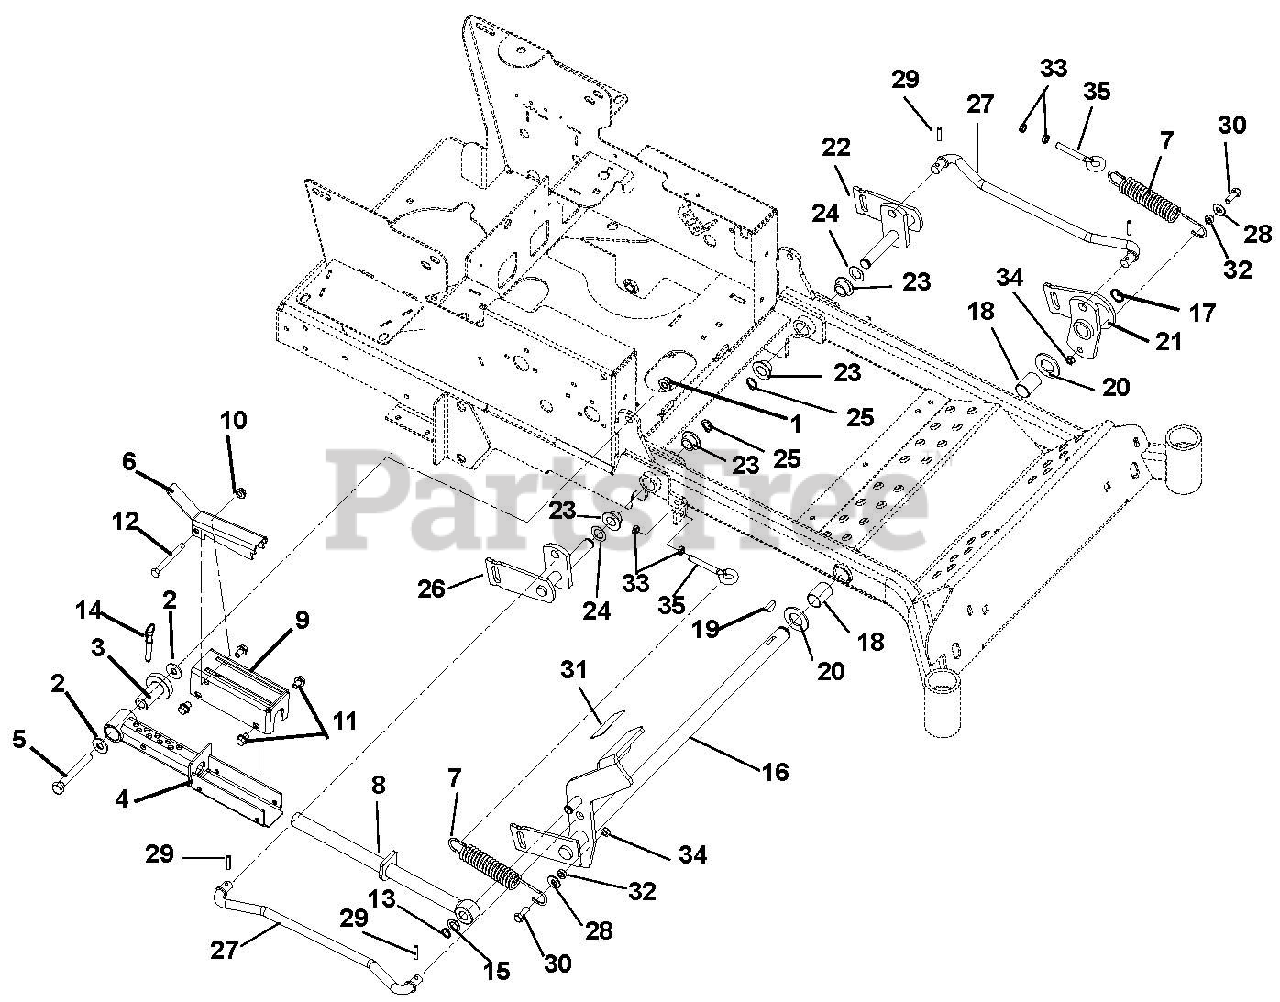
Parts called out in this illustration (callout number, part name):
1	Nut, Locking Top Flange .50-13
2	Washer, Flat Steel .531 x 1.25 x .10
3	Bearing, Pedestal
4	Weldment, Mechanical Lift
5	Bolt, Hex .50-13 x 3.75 Grade 5
6	Lock-Up, Mechanical Lift
7	Spring, Tension .162 x 1.25 x 8.25 Weldment 25
8	Weldment, Mechanical Lift Shaft
9	Weldment, Mechanical Lift Cover
10	Nut, Nyloc Flange 3/8-16
11	Screw, Tapping .38-16 x .50 Hex Washer Head
12	Bolt, Hex .38-16 x 3.25 Grade 5
13	Ring, Retaining External .625 x .050
14	Pin, Spring Ball .375 O.D. x 1.50
15	Washer, Flat Steel .630 x .005 x .062
16	Weldment, Foot Operated Deck Lift
17	Ring, Retaining External 1.00 x .078
18	Bushing 1.00 ID x 1.125 OD x 1.50
19	Key, Woodruff .25 x 1.00
20	Washer, Flat Steel 1.062 x 2.0 x .134
21	Weldment, Left Hand Mower Lift Arm
22	Weldment, Left Hand Rear Mower Lift Arm
23	Bushing, Flange Nylon .762 x 1.0 x .580 x 1.48
24	Washer, Hardened Steel .758 x 1.23 x .031
25	Ring, Retaining External .689 x .077
26	Weldment, Right Hand Rear Mower Lift Arm
27	Rod, Lift Assist
28	Washer, Flat Steel .438 x 1.00 x .083
29	Pin, Roll .25 x 1.25 Stainless Steel
30	Bolt, Hex .38-16 x 1.00 Grade 5
31	Grip, Pedal
32	Bushing, Sleeve .377 x .624 x .235
33	Nut, Hex-Jam .375-16
34	Nut, Locking-Jam-Center .375-16
35	Bolt, Eye .375-16 x 2.50
